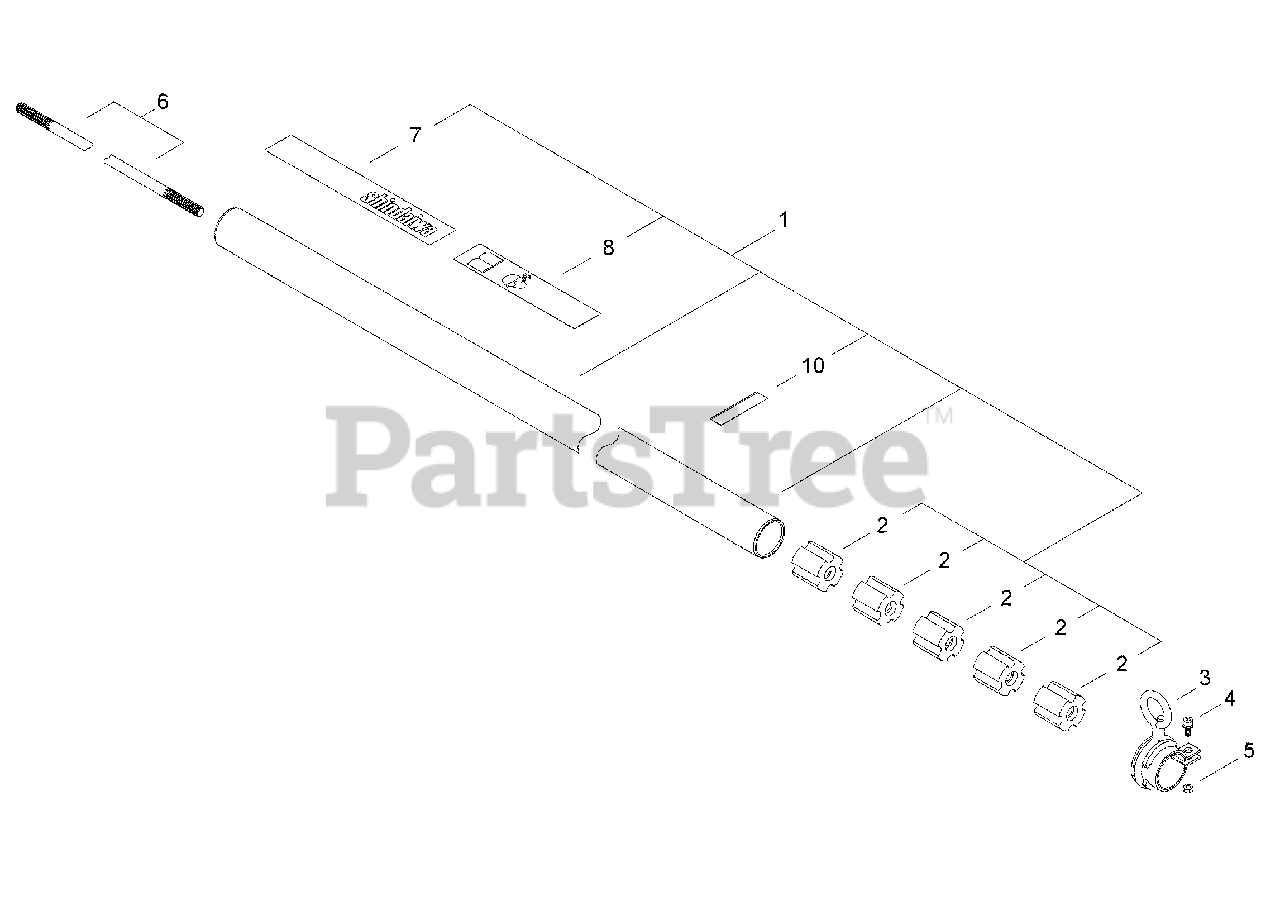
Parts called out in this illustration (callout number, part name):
1	MAIN PIPE ASSY
2	BUSHING
3	HANGER, SWIVEL
4	BOLT M5×12
5	NUT M5
6	MAINSHAFT
7	LABEL, SHINDAIWA PROFESSIONAL
8	LABEL, CAUTION (BLADE CAPABLE)
10	LABEL - ALIGNMENT
